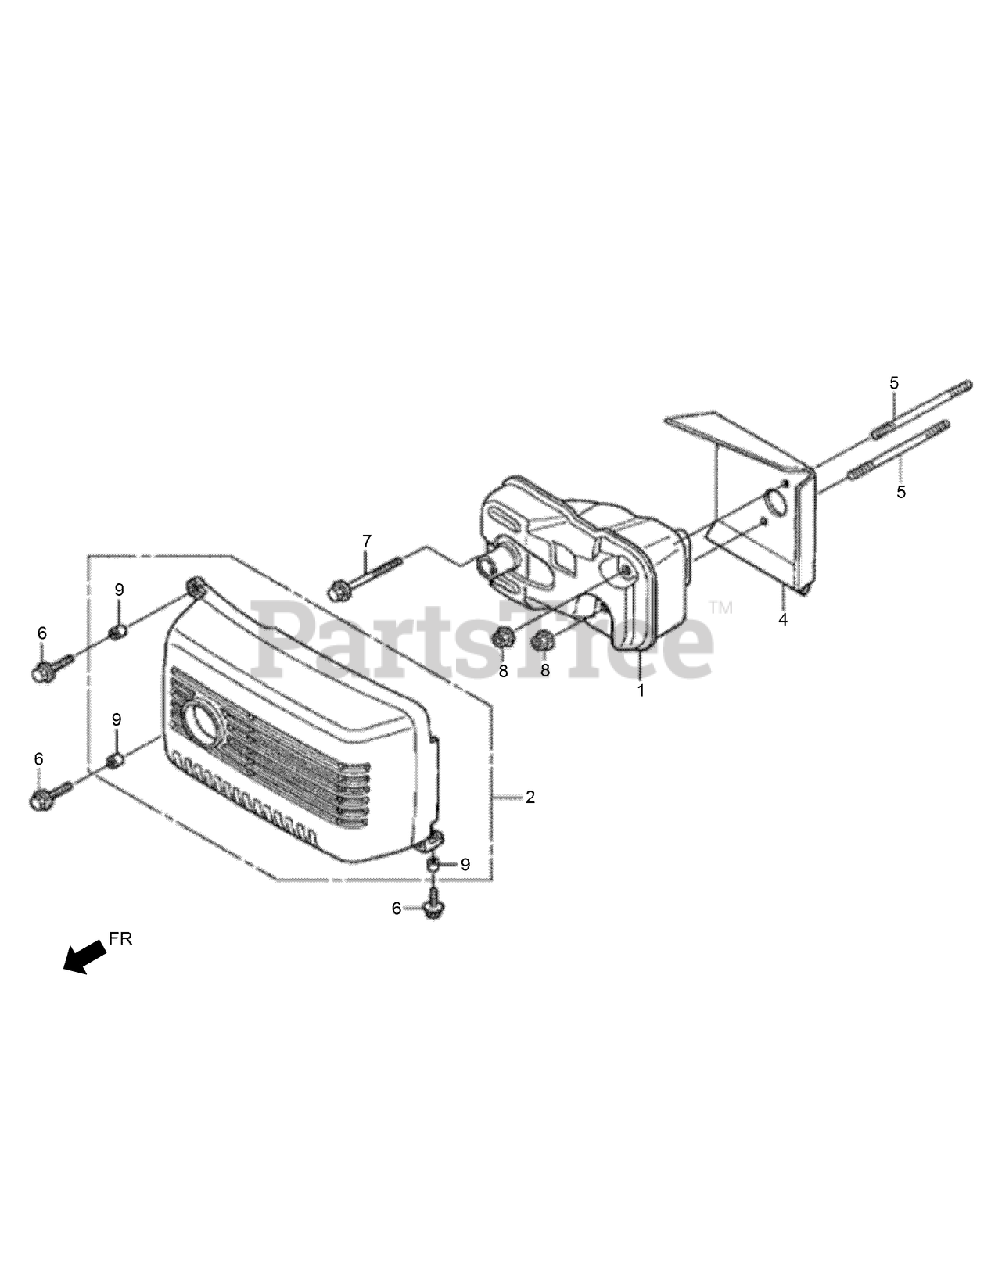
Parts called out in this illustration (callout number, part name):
1	MUFFLER
2	MUFFLER PROTECTOR ASM
4	GUIDE-AIR
5	BOLT-STUD-5X55
6	BOLT-FLANGE-5X16
7	BOLT-FLANGE-5X35
8	NUT-SELF-LOCK-5MM
9	COLLAR-TOP COVER
